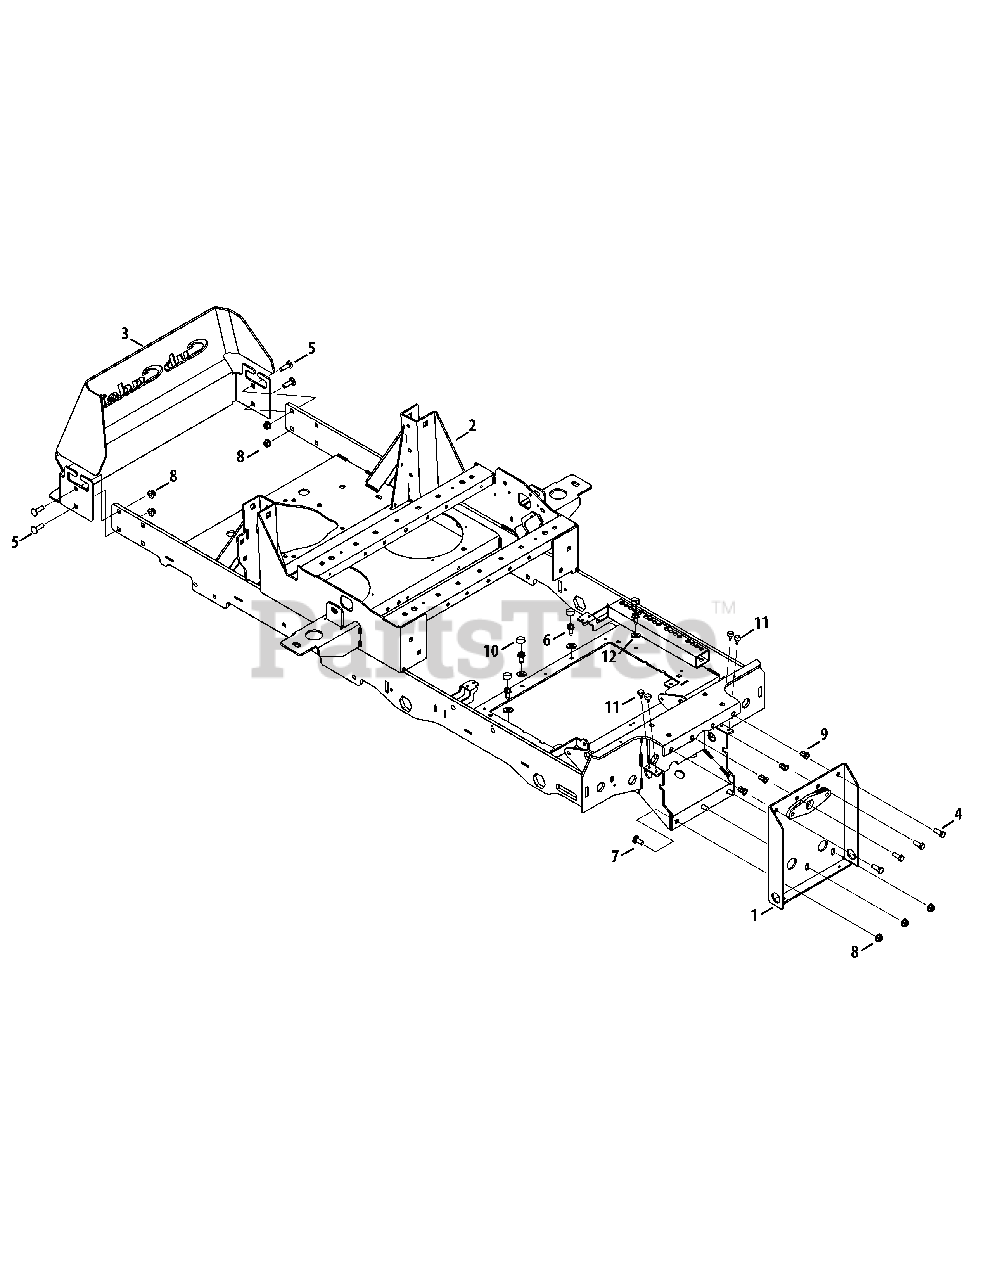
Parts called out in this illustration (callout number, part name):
1	Front Axle Bracket Assembly
2	Frame Assembly
4	Hex Cap Screw, 3/8-16 x 1.00
5	Carriage Bolt, 3/8-16 x 1.25
6	Screw, 3/8-16 x .750
7	Carriage Bolt, 3/8-16 x 1.00
8	Nylock Nut, 3/8-16
9	Rivet Nut, 3/8-16
10	Slide Cap
11	Bumper, .62 Dia. x .3
12	Washer, .406 x 1.00 x .105
